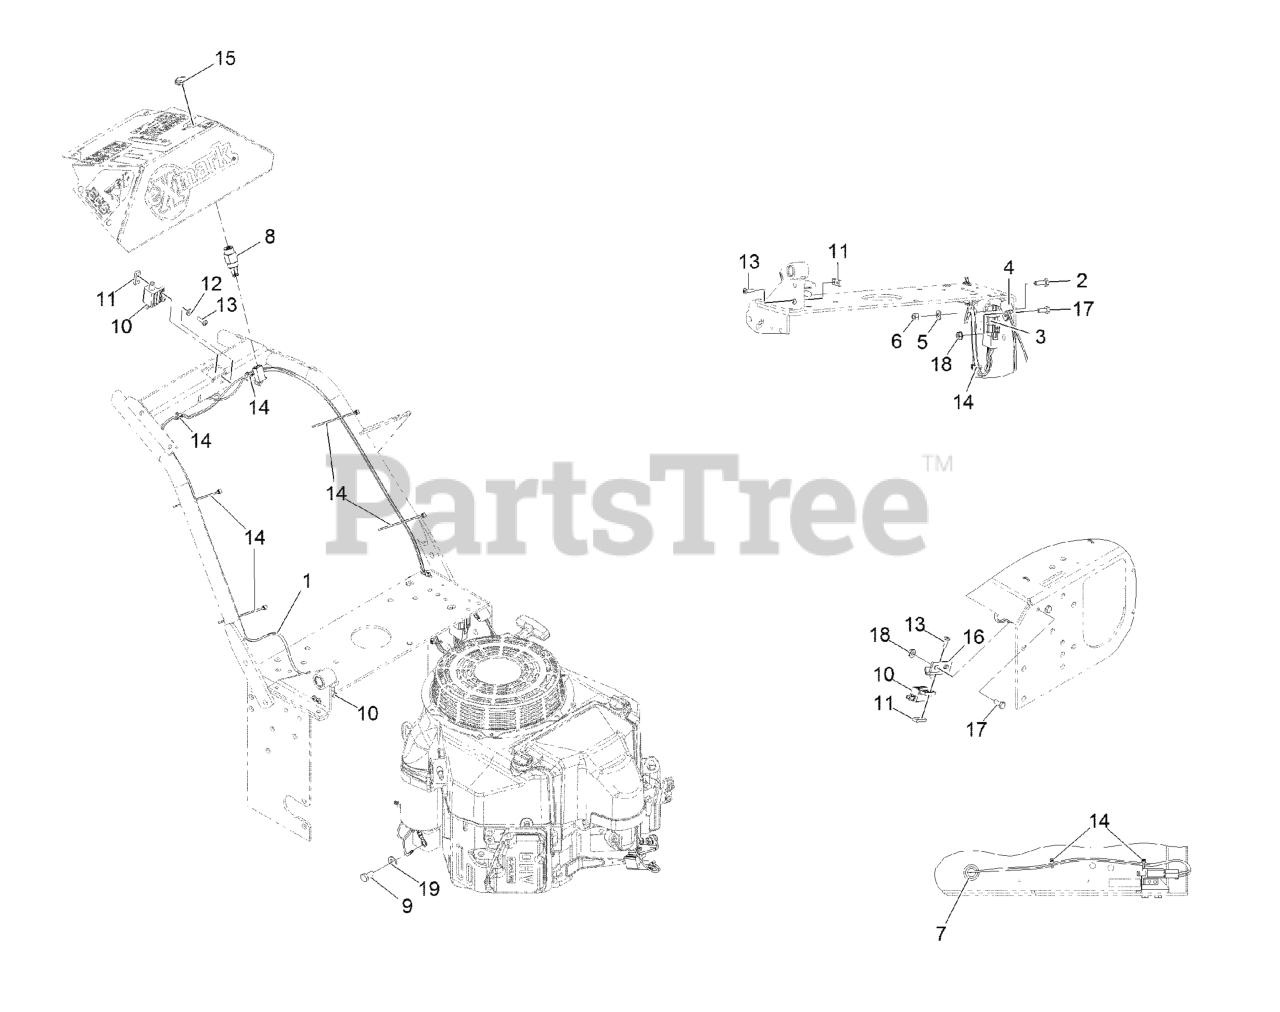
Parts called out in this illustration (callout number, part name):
1	HARNESS-WIRING
2	SCREW-HH
3	MODULE-INTERLOCK
4	CLIP-LOOM
5	WASHER-FLAT
6	NUT-LOCK, NI
7	GROMMET
8	SWITCH & KEY (INCLUDES NU
9	SCREW-HH
10	SWITCH-OPEN, NORMALLY
11	PLATE-TAPPED
12	WASHER-FLAT
13	SCREW-PPH
14	TIE-CABLE
15	NUT-SWITCH, IGNITION
16	BRACKET-SWITCH, BLADE
17	SCREW-HH
19	WASHER-PLAIN
